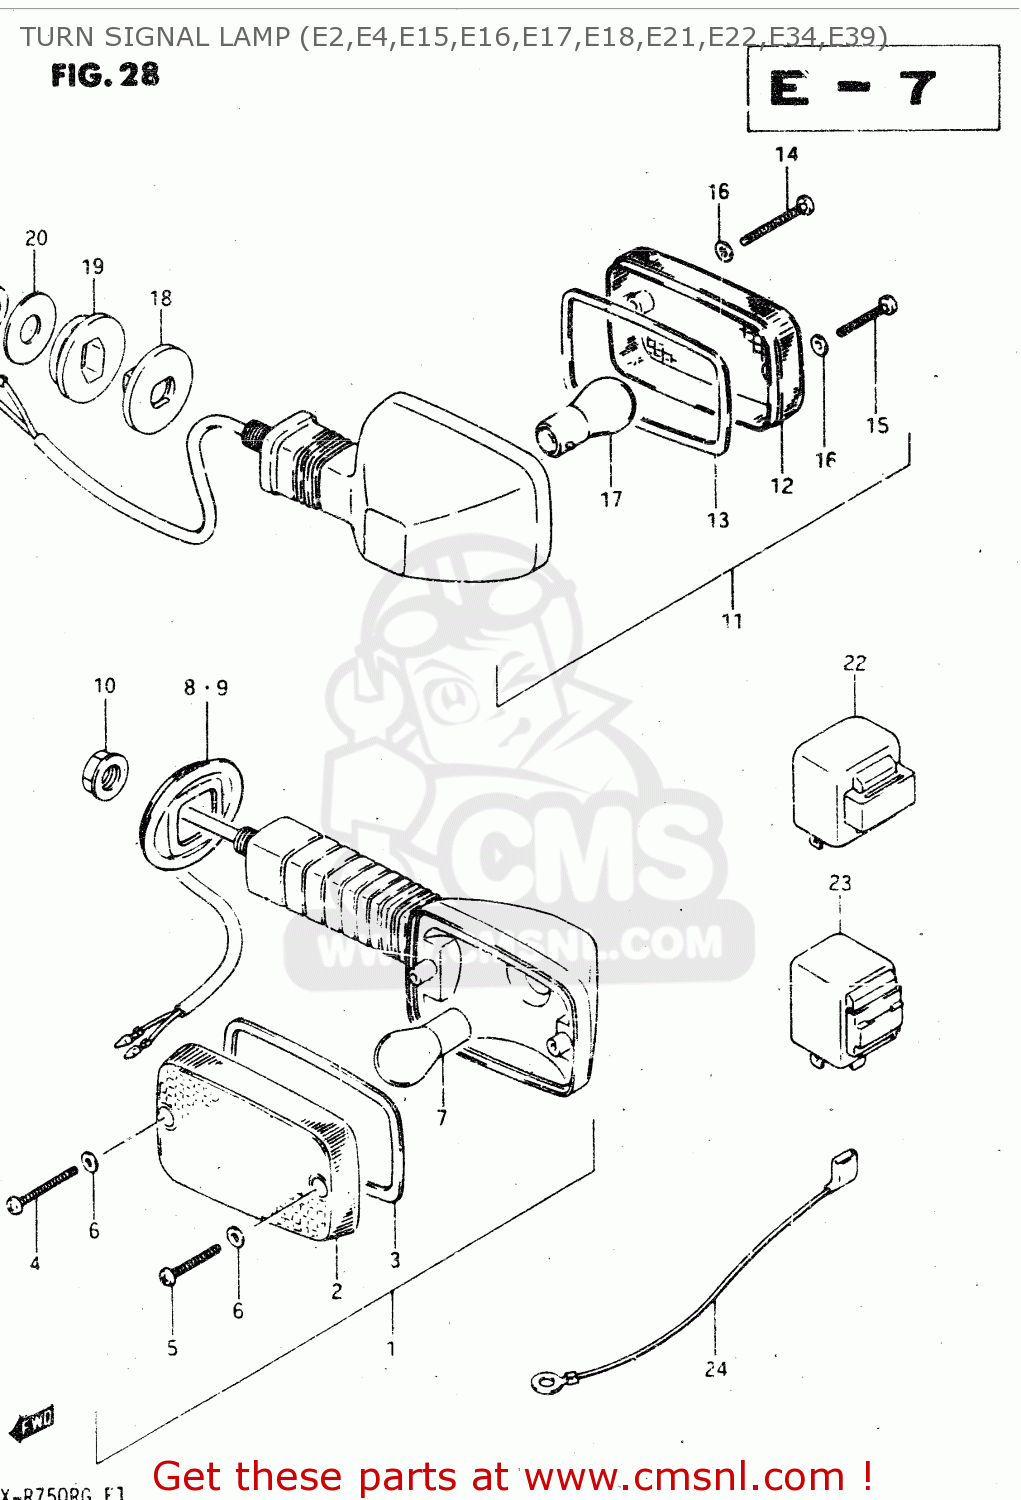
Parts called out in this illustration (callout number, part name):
1	LAMP ASSY, FRONT TURN SIGNAL
2	LENS,FR
3	GASKET (NAS)
4	SCREW,TURN SIG LENS FITTING
5	SCREW
6	GASKET (NAS)
7	BULB(12V21W)
8	GROMMET, FRONT RH
9	GROMMET, FRONT LH
10	NUT
11	LAMP ASSY, REAR TURN SIGNAL
12	LENS
13	GASKET (NAS)
14	SCREW,TURN SIG LENS FITTING
15	SCREW
16	GASKET (NAS)
17	BULB(12V21W)
18	CUSHION
19	SPACER
20	SPACER
21	NUT
22	RELAY ASSEMBLY,TURN SIGNAL
23	RELAY ASSY,TUR
24	LEAD WIRE
